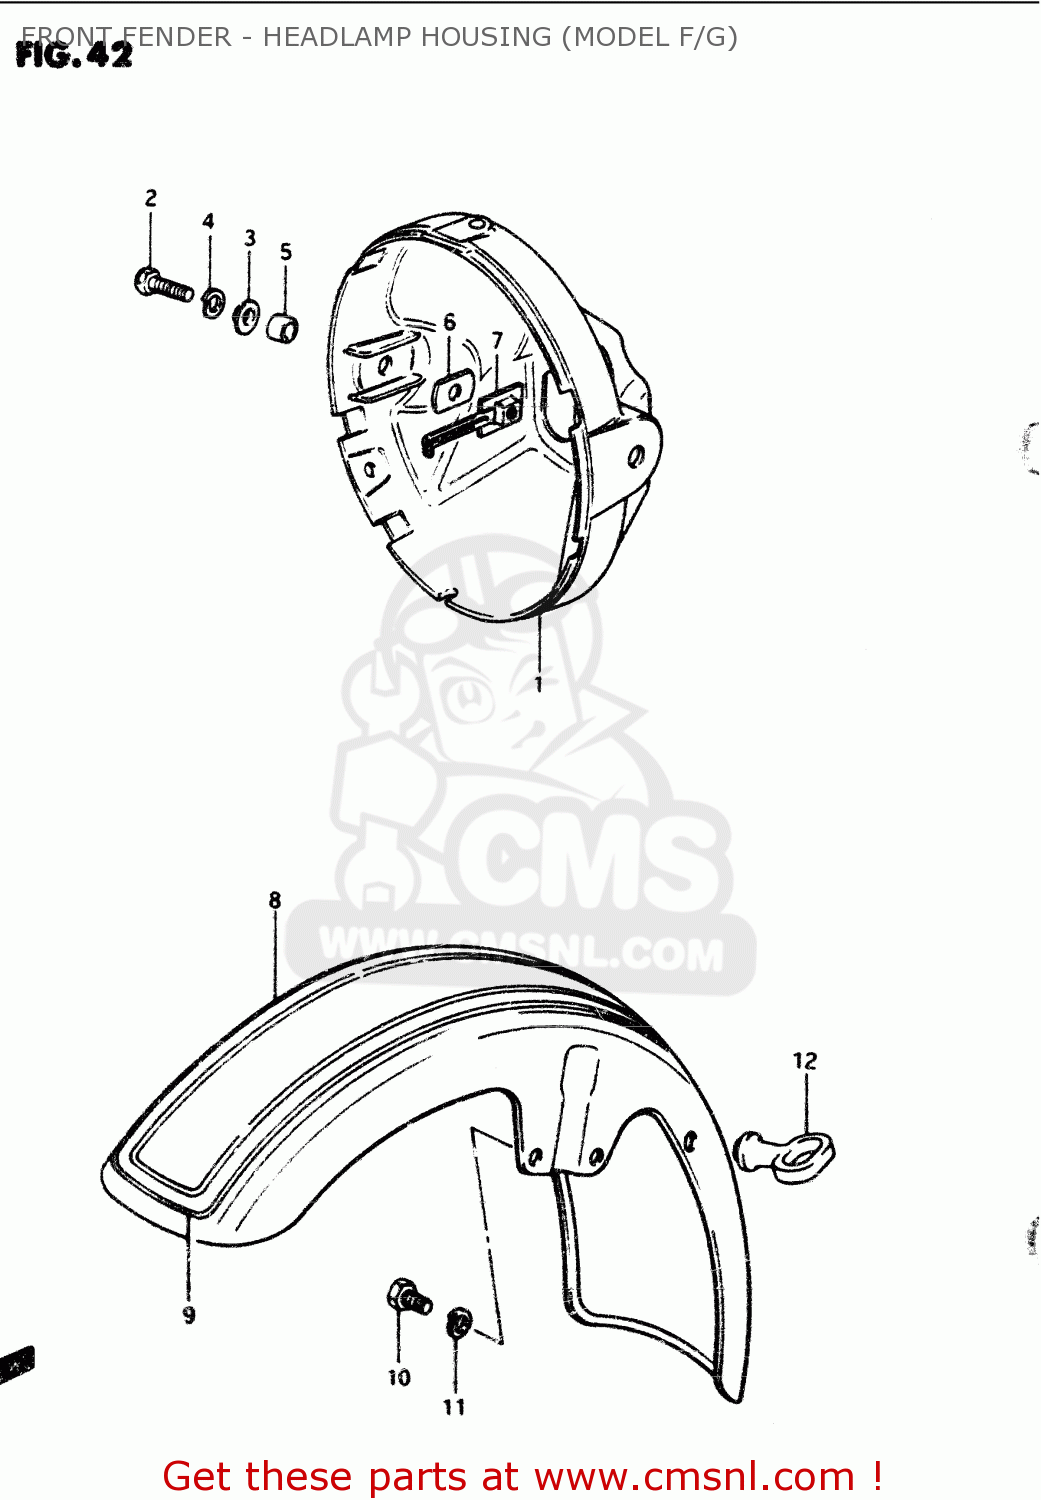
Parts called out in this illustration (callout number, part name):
1	HOUSING,HEADLAMP
2	BOLT
3	WASHER
4	LOCK WASHER
5	SPACER (8.8X12X7)
6	CUSHION
7	PLATE,HEADLAMP HOUSING
8	FENDER, FRONT (WHITE/SILVER)
9	TAPE SET
10	BOLT
11	LOCK WASHER
12	GUIDE,CABLE
